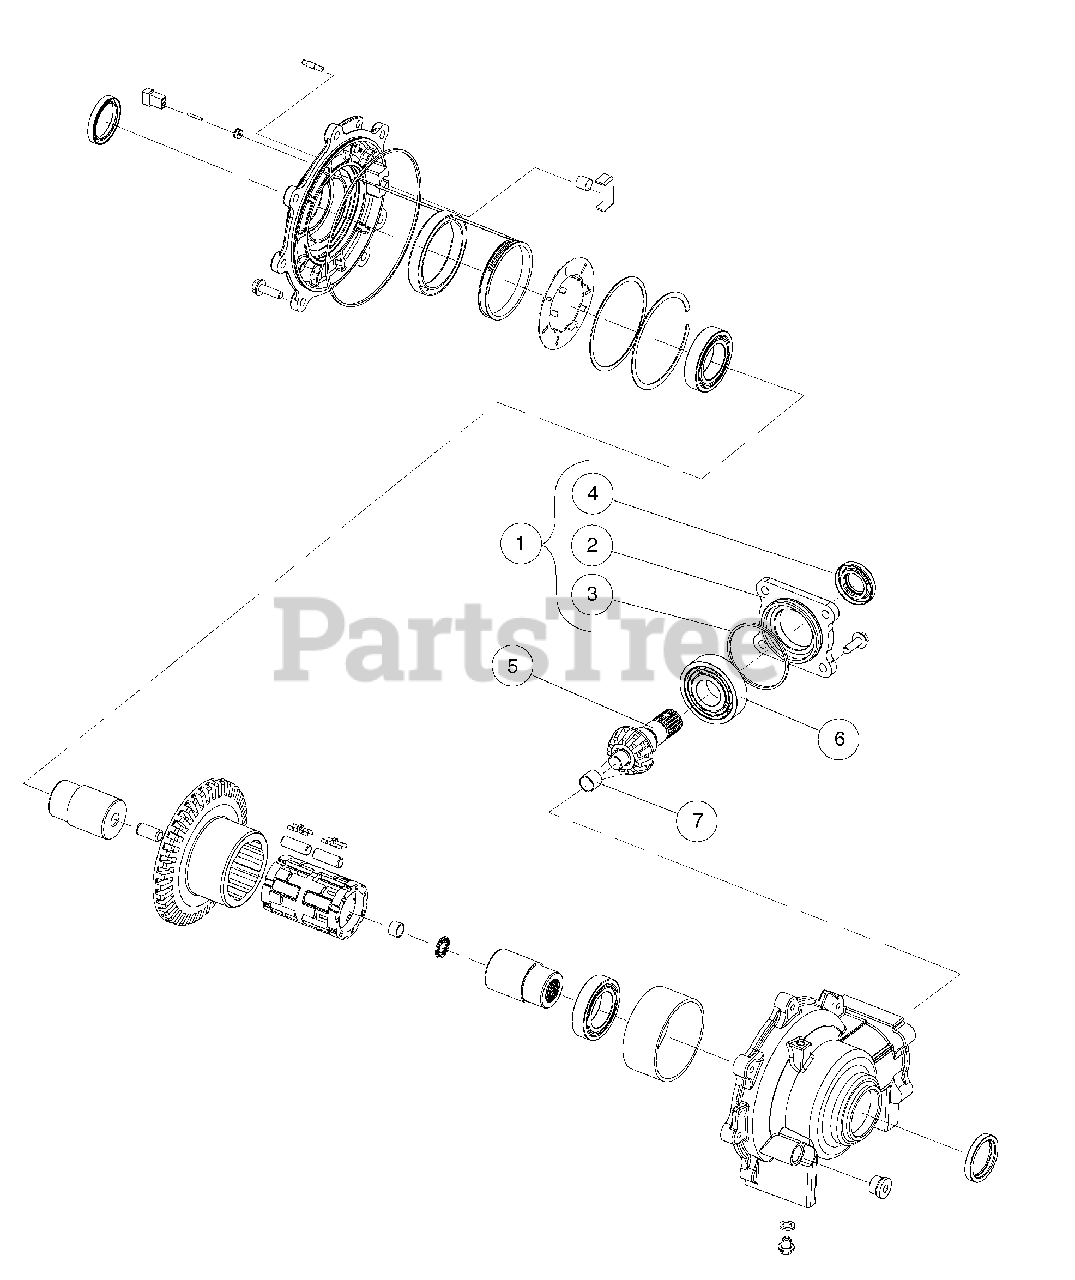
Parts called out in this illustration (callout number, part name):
1	Kit, Assy, Input Cover Plate
2	Cover, Input, Machined
3	O-Ring
4	Oil Seal, Triple-Lipped
5	Shaft, Pinion, Machined
6	Bearing, Ball
7	Bushing, Plain 16 Id X 15 Wide
